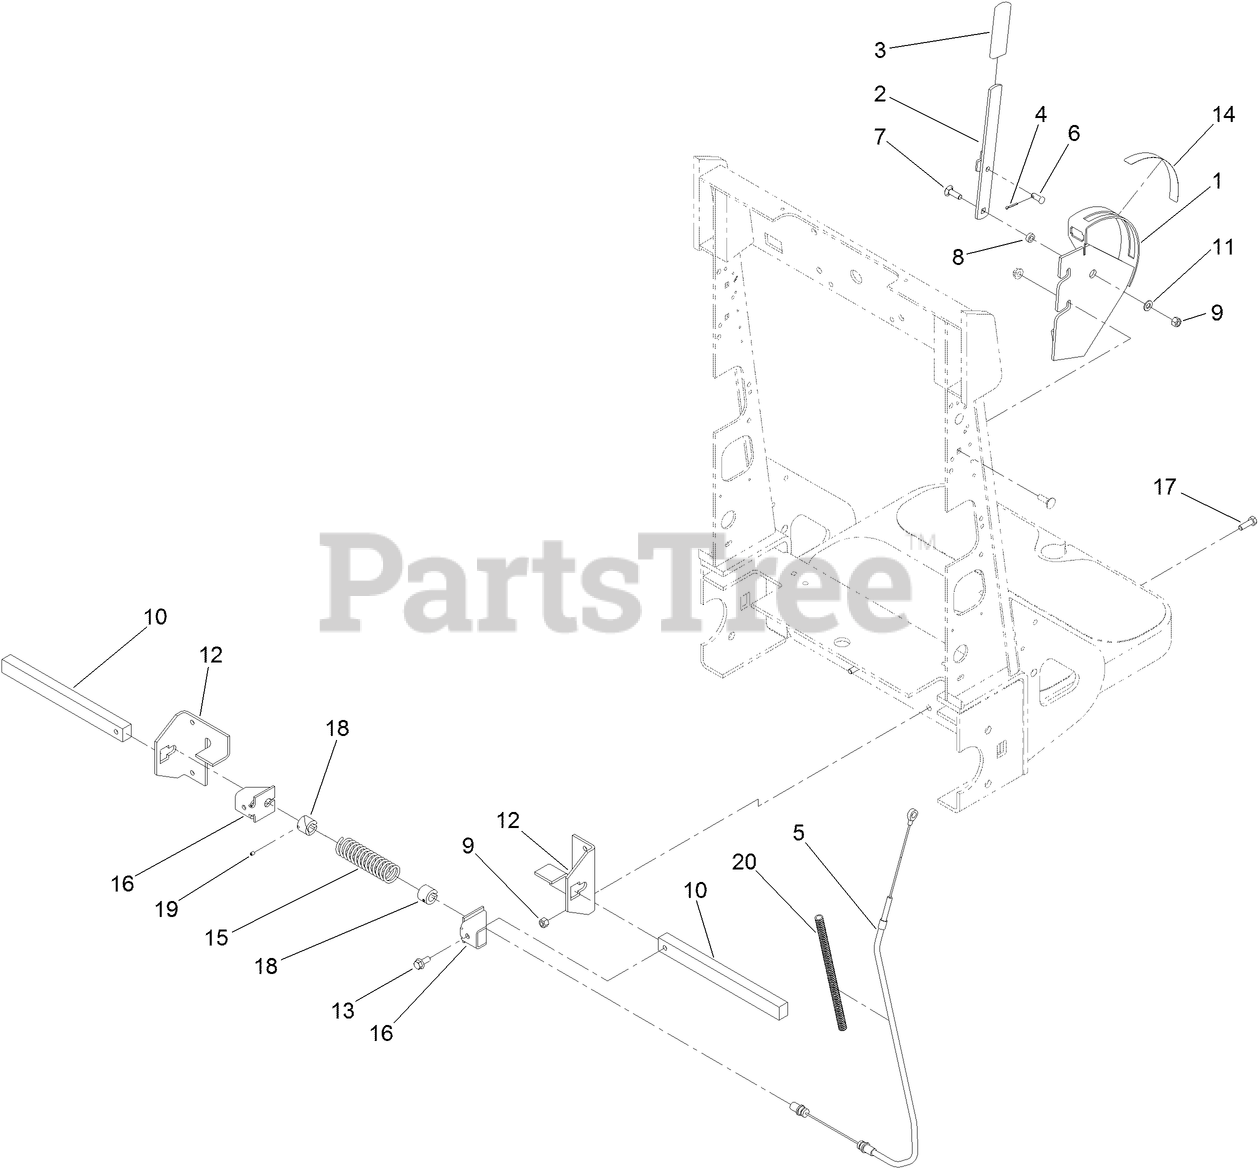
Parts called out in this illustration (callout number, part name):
1	PLATE-BRAKE
2	LEVER-BRAKE
3	GRIP-HANDLE
4	PIN-COTTER
6	PIN-CLEVIS
7	SCREW-CARR
8	HUB-LEVER
9	NUT-LOCK, NI
10	BAR-BRAKE
11	WASHER-PLAIN
12	BRACKET-BRAKE
13	SCREW-FLANGE
14	DECAL-BRAKE
16	BRACKET-CABLE
17	SCREW-HH
18	Tube-Guide
19	SCREW-HSH
20	TUBE-CONVOLUTED
